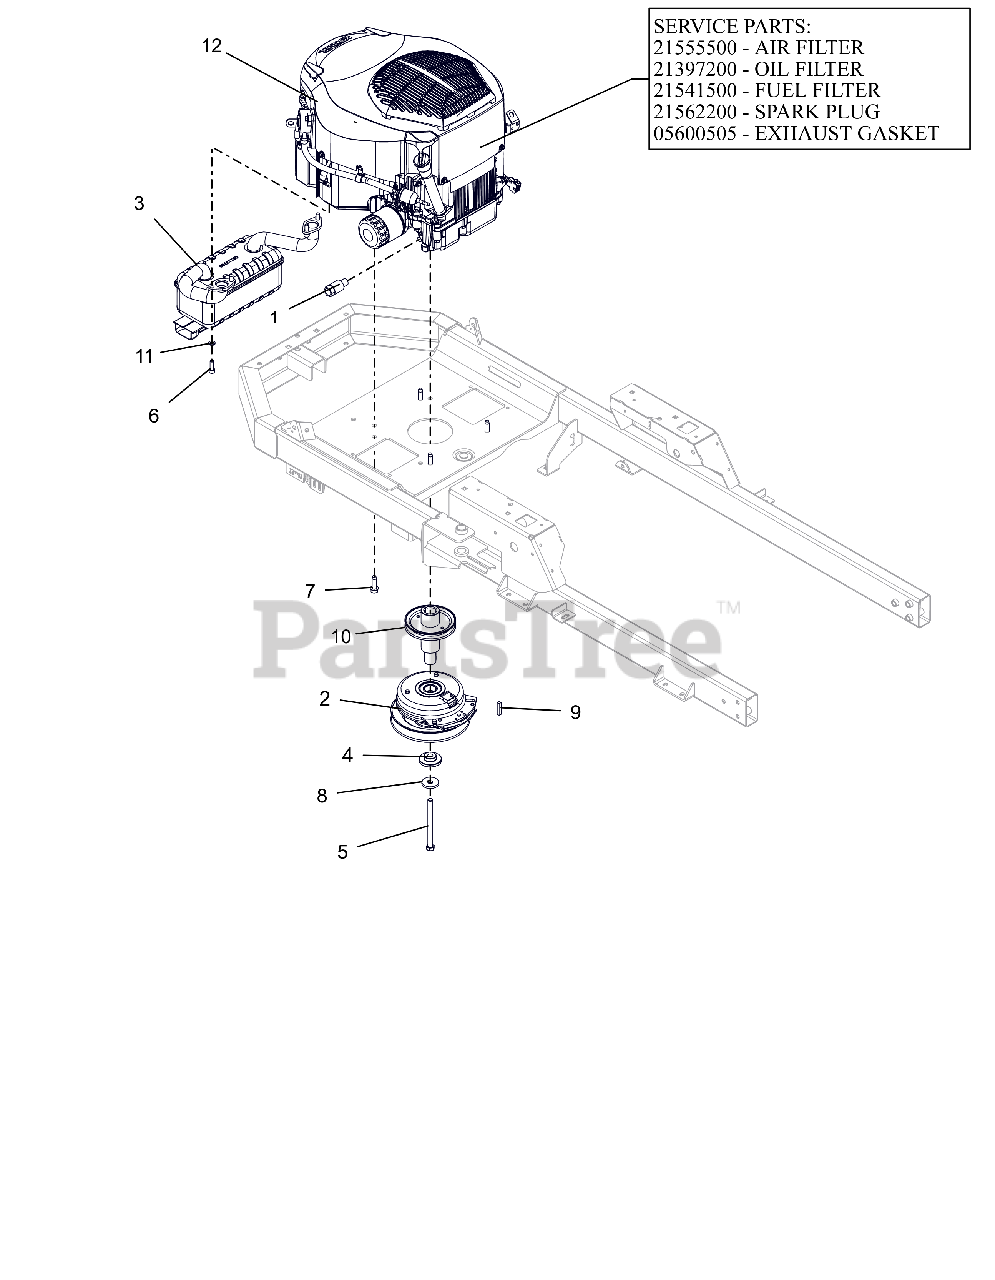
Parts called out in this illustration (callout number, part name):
1	DRAIN, OIL
2	CLUTCH,105FTLB MONOPOLE 6.83"
3	MUFFLER, KOHLER
4	BSHG-FLG .469X1.06X.574X2.0
5	BLT-HEX.438-20X5 GR8 YZ NYTORQ
6	SCR-CAP .31-18X.88 S/HD G8 ZCC
7	SCR,TAP .375-16X1.25HWH TR ZCC
8	WASHER, 7/16" SPRING DISK
9	KEY-SQ .25 X 1.25 X .25 SAE
10	WLDMT, DRIVE SHEAVE (LG XL)CZC
11	WSHR,LK-REG .312X.078 ZCC
12	ENGINE, KOHLER 22HP TWIN
12	AIR CLEANER, KOHLER
12	FILTER, OIL - KOH CV20
12	FILTER, FUEL
12	PLUG, SPARK (RFI)
12	GASKET, MUFFLER COURAGE TWIN
